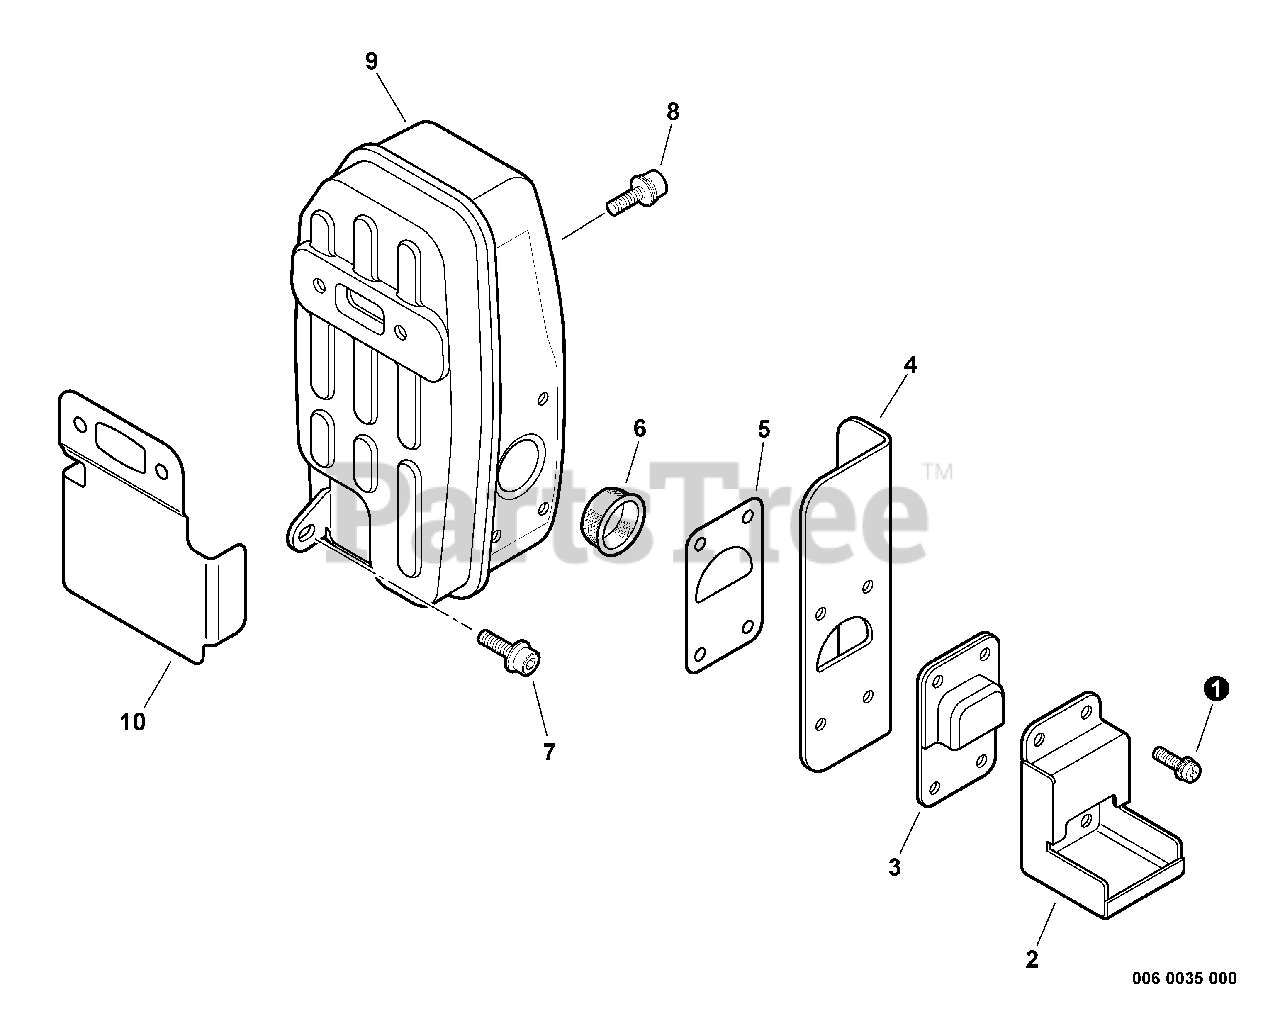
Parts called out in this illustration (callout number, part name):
1	SCREW 4×14
2	GUIDE, EXHAUST
3	GUIDE, EXHAUST
4	HEAT SHIELD, EXHAUST
5	GASKET, EXHAUST
6	SCREEN, SPARK ARRESTER
7	BOLT 5×14
8	BOLT, FLANGE 6×20
9	MUFFLER
10	HEAT SHIELD, EXHAUST
